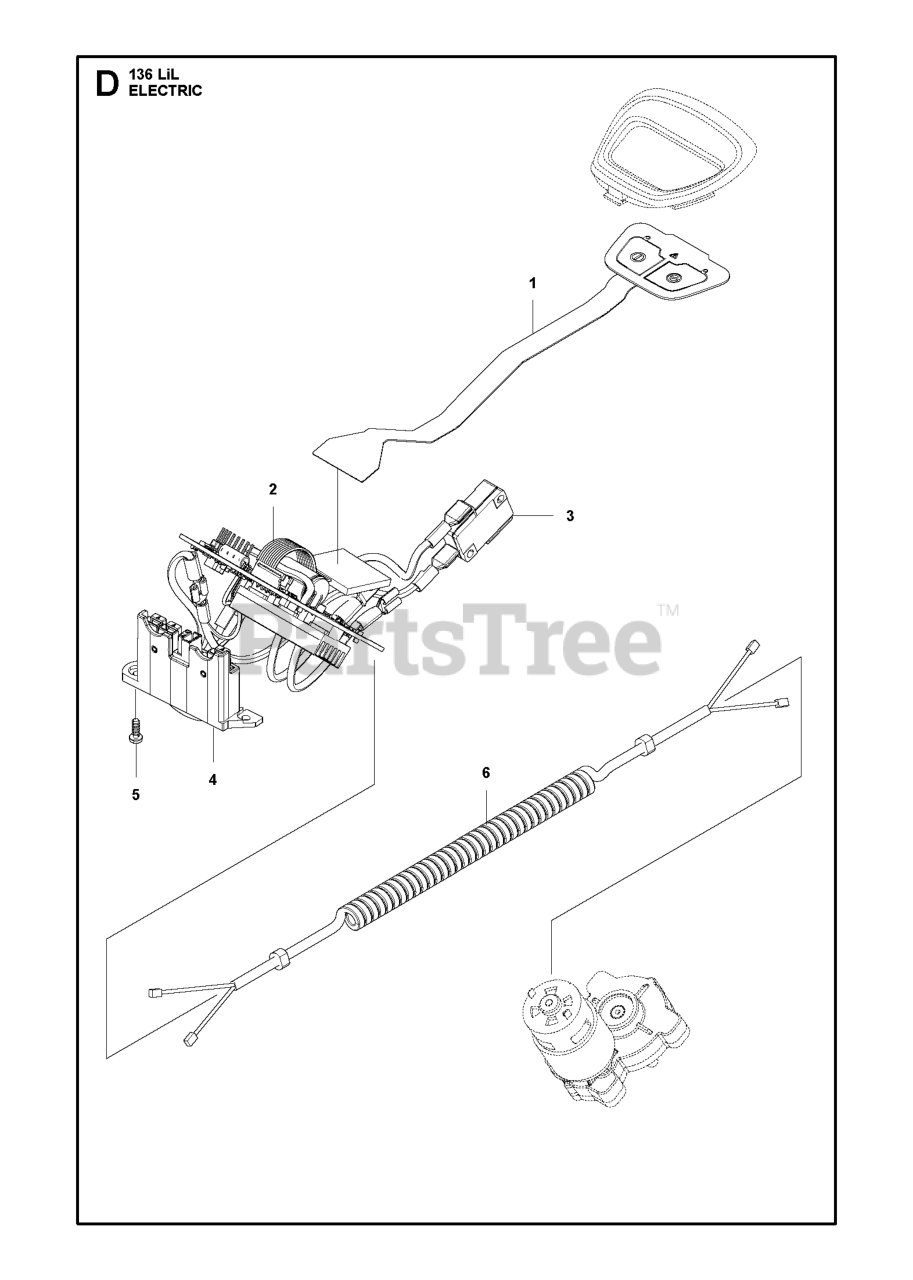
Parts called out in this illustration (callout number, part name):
1	KEYPAD TRIMMER
2	UNIT ,TRIMER CONTROL
3	MICRO SWITCH
4	TERMINAL BLOCK ASSEMBLY
5	SCREW ST3X8
6	CABLE SPIRAL
